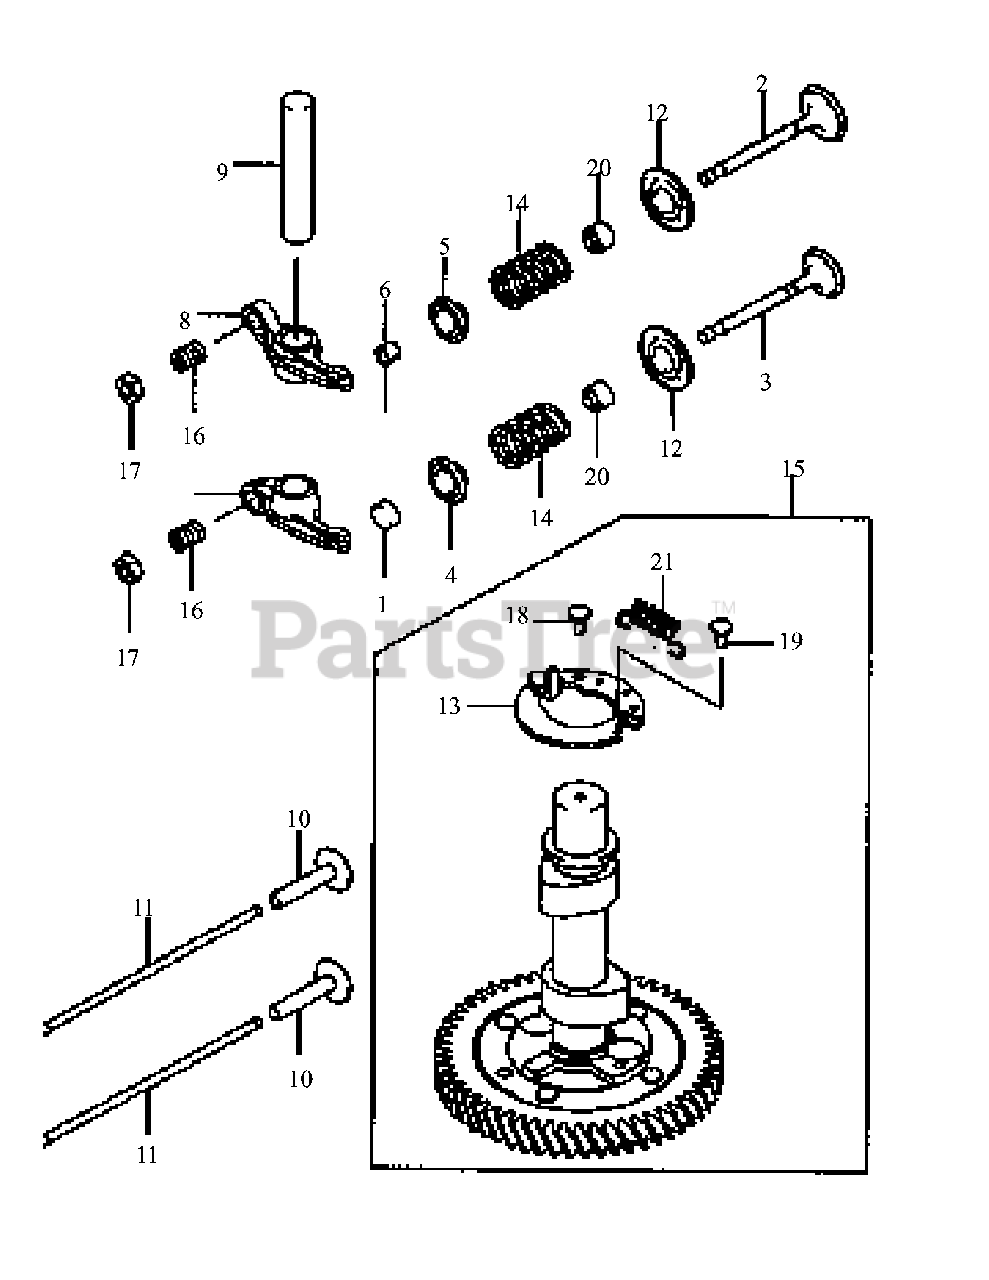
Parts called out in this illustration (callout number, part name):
2	Valve, Intake
3	Valve, Exhaust
4	Retainer, Valve Spring
5	Retainer, Valve Spring
9	Shaft, Rocker
14	Spring, Engine Valve
20	Seal, Oil
